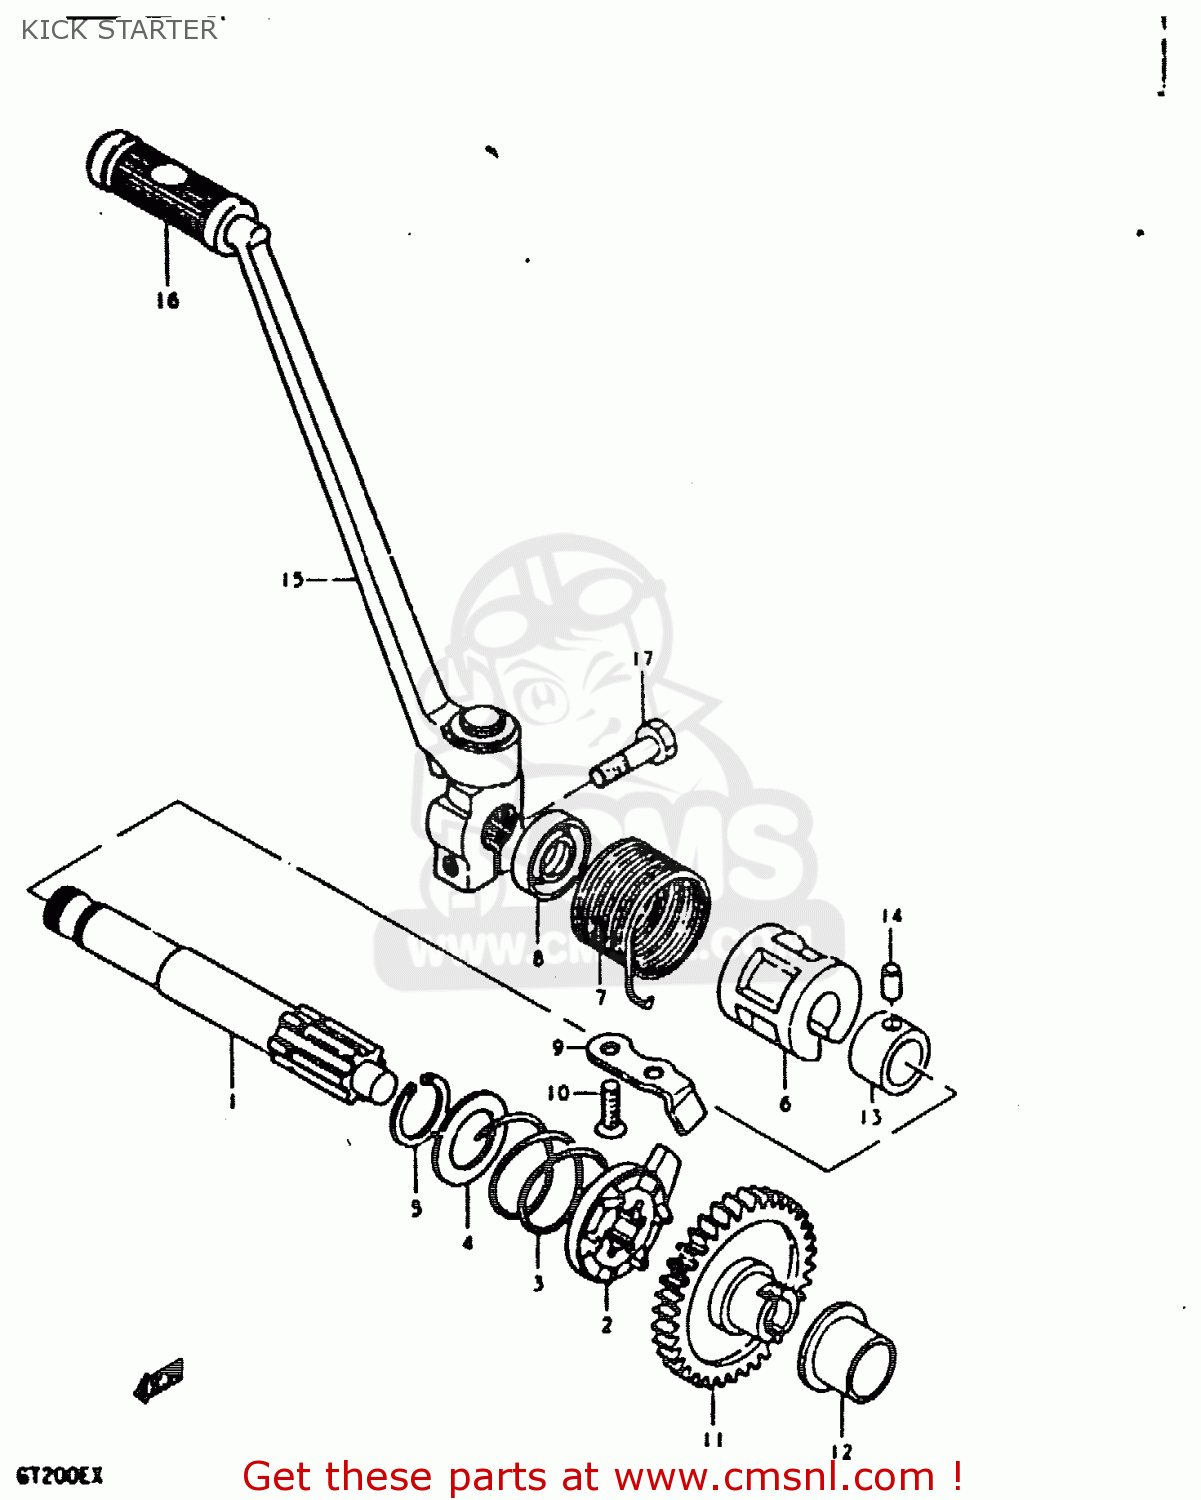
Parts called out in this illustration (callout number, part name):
1	SHAFT, KICK STARTER
2	STARTER,KICK
3	SPRING
4	PLATE
5	CIRCLIP
6	GUIDE,KICK SHAFT SPRING
7	SPRING
8	SEAL,OIL(16X30X8)
9	GUIDE,KICK STARTER
10	SCREW
11	GEAR, KICK STARTER DRIVE
12	BUSHING
13	BUSHING
14	PIN
15	LEVER ASSY,KICK STARTER
16	RUBBER,KICK STARTER PEDAL
17	BOLT
